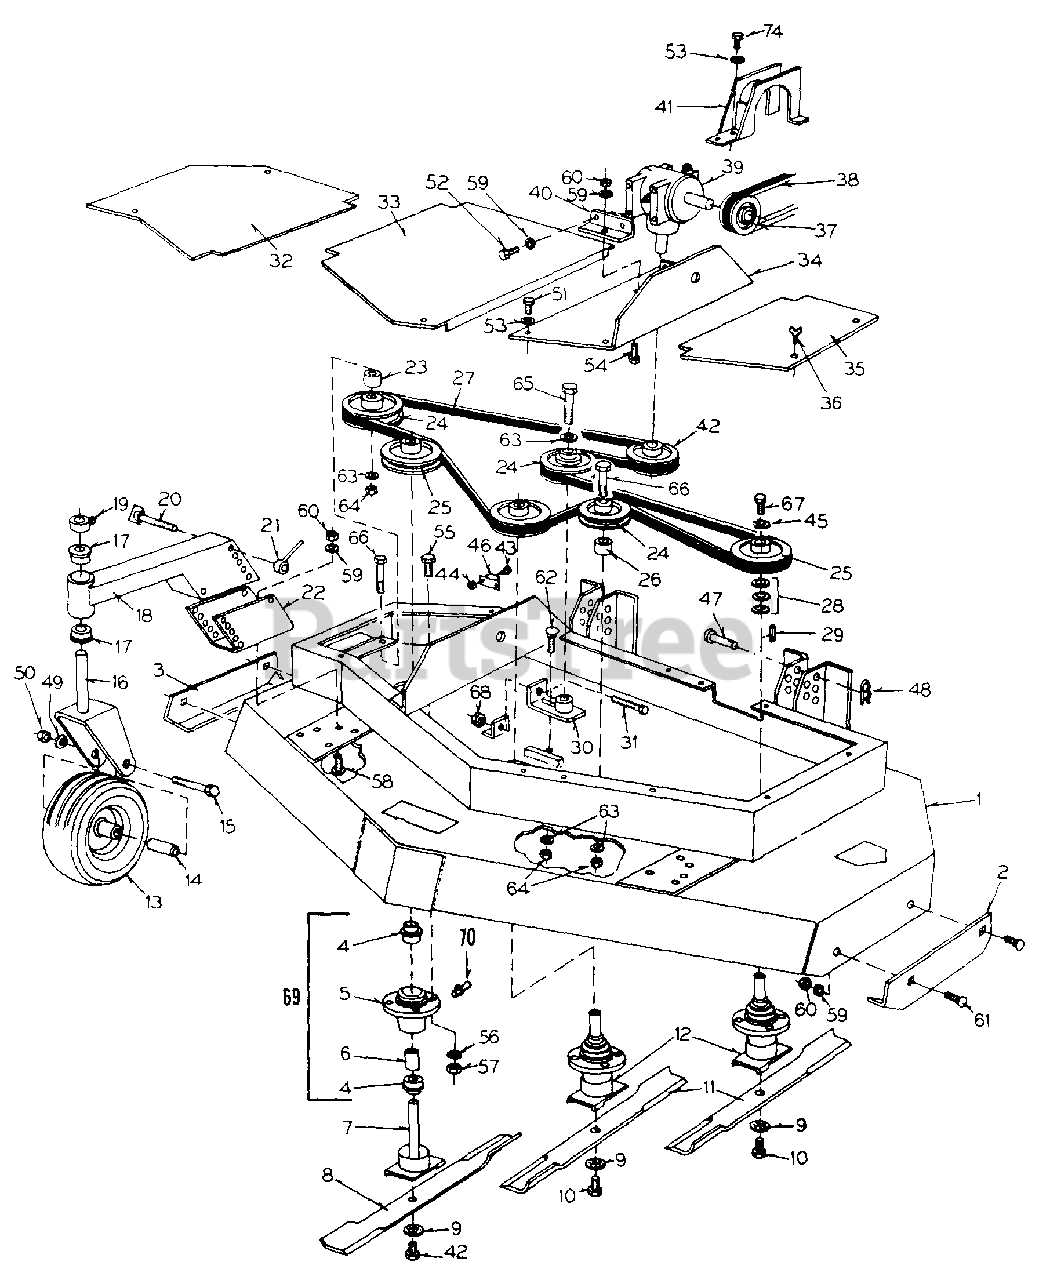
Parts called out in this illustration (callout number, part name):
1	DECK - rear discharge 52"
2	SHOE - skid L.H.
3	SHOE - skid R.H.
4	BEARING - spindle 7/8
5	HOUSING - spindle
6	SPACER - spindle
7	SHAFT - spindle L.H. rotation
8	BLADE - L.H. rotation
9	WASHER - blade
10	BOLT - 3/8"-24 x 1-1/4"
11	BLADE - R.H. rotation
12	SHAFT - spindle
14	AXLE - gauge wheel
15	BOLT - 1/2"-13 x 6-1/2"
16	FORK - gauge wheel
18	MOUNT - gauge wheel
19	COLLAR - set 1"
20	BOLT - wing 3/8"-16 x 4-1/2"
21	NUT - gauge wheel handle 3/8"-16
22	BRACKET - gauge wheel mount
23	SPACER - idler pulley
24	PULLEY - idler 5"
25	PULLEY - spindle 4-1/2"
26	SPACER - idler pulley
28	WASHER - spacer
29	KEY - 3/16" x 3/16" x 1"
30	TIGHTENER - belt
31	BOLT - 1/4" - 20 x 4"
33	COVER - center
34	MOUNT - gear box
37	PULLEY - gear box input
38	BELT - drive
39	GEAR BOX - angle drive
40	ANGLE - gear box mount
42	BOLT - 3/8"-24 x 1-1/4" L.H.
43	SCREW - #10-32 x 1/2"
44	NUT - lock #10-32
45	WASHER - spindle
46	BREAKER - circuit 10 amp
47	PIN - clevis 1/2" x 1-1/2"
48	PIN - cotter, hair
49	LOCKWASHER - 1/2"
50	NUT - 1/2"-13
51	BOLT - 1/4"-20 x 3/4"
52	BOLT - 5/16"-18 x 1"
53	LOCKWASHER - 1/4"
54	BOLT - 5/16"-18 x 3/4"
55	BOLT - 7/16"-14 x 1-1/4"
56	LOCKWASHER - 1/16"
57	NUT - 7/16"-14
58	BOLT - carriage 5/16"-18 x 1"
59	LOCKWASHER - 5/16"
60	NUT - 5/16"
61	BOLT - carriage 5/16"-18 x 3/4"
62	BOLT - carriage 3/8"-16 x 1"
63	LOCKWASHER - 3/8"
64	NUT - 3/8"-16
65	BOLT - 3/8"-16 x 1-1/4"
66	BOLT - 3/8"-16 x 2-1/2
67	BOLT - 5/16"-24 x 3/4"
68	NUT - lock 1/4"-20
69	HOUSING ASSEMBLY - spindle
70	FITTING - grease 1/4"-28
